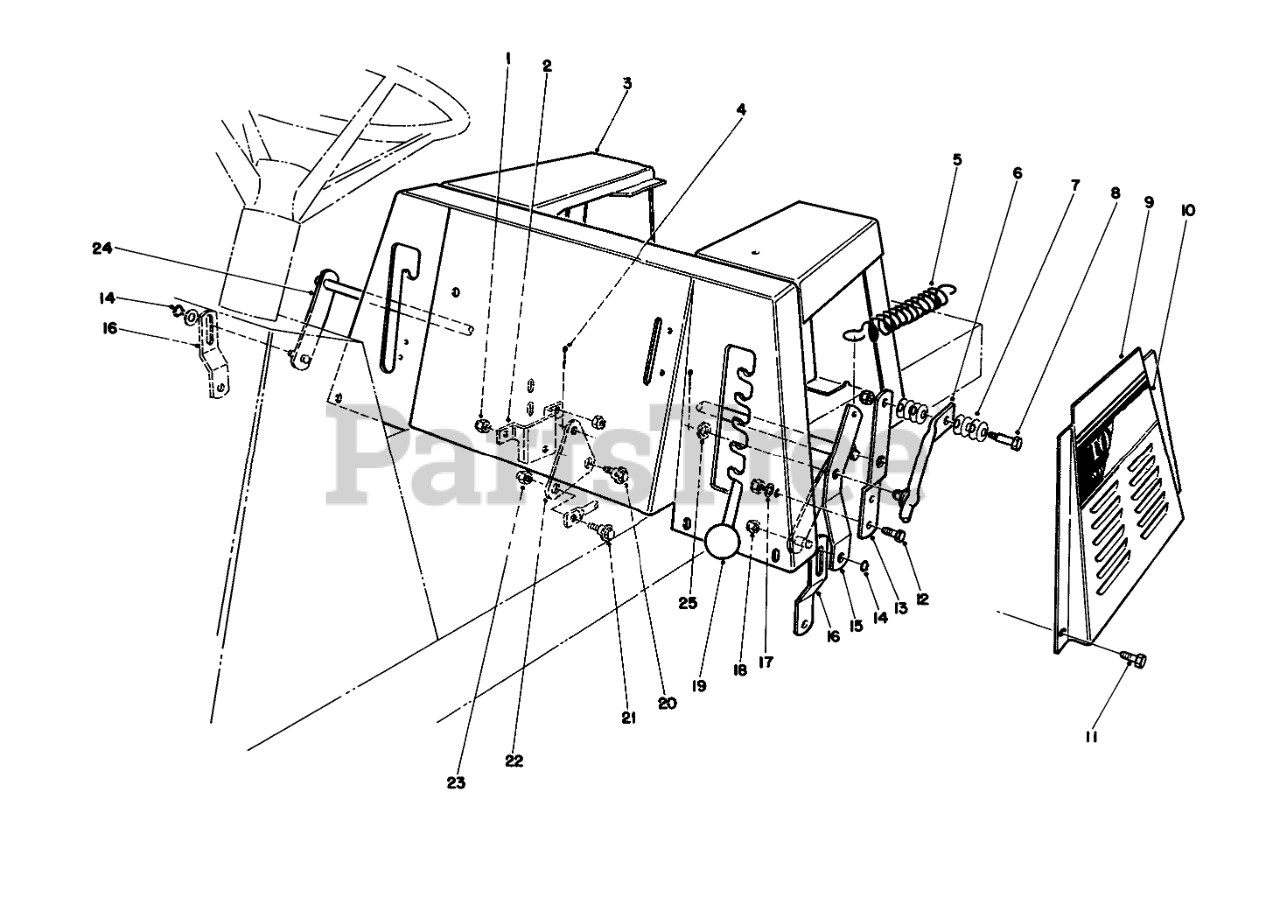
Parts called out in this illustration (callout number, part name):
1	NUT-LOCK, NI
2	BRKT-B.CRANK MTG
3	SEAT BODY WA R
4	PIN-COTTER
5	SPRING-EXTENSION
6	HOC LEVER WA B
7	WASHER-BELLEVILLE
8	BOLT-SHOULDER
9	L/H SEAT BASE PANELR
10	DECAL - LH TORO 10-32
11	SCREW-HH
12	SCREW-HH
13	Bracket
14	RING-RETAINING
15	Bracket-H.O.C., Engage
16	Link-Deck Suspension
17	WASHER-PLAIN
18	NUT-LOCK, NI
20	SCREW-SHOULDER
21	SCREW-SHOULDER
22	BELLCRANK
23	NUT-HEX
24	Arm
25	WASHER-FLAT
